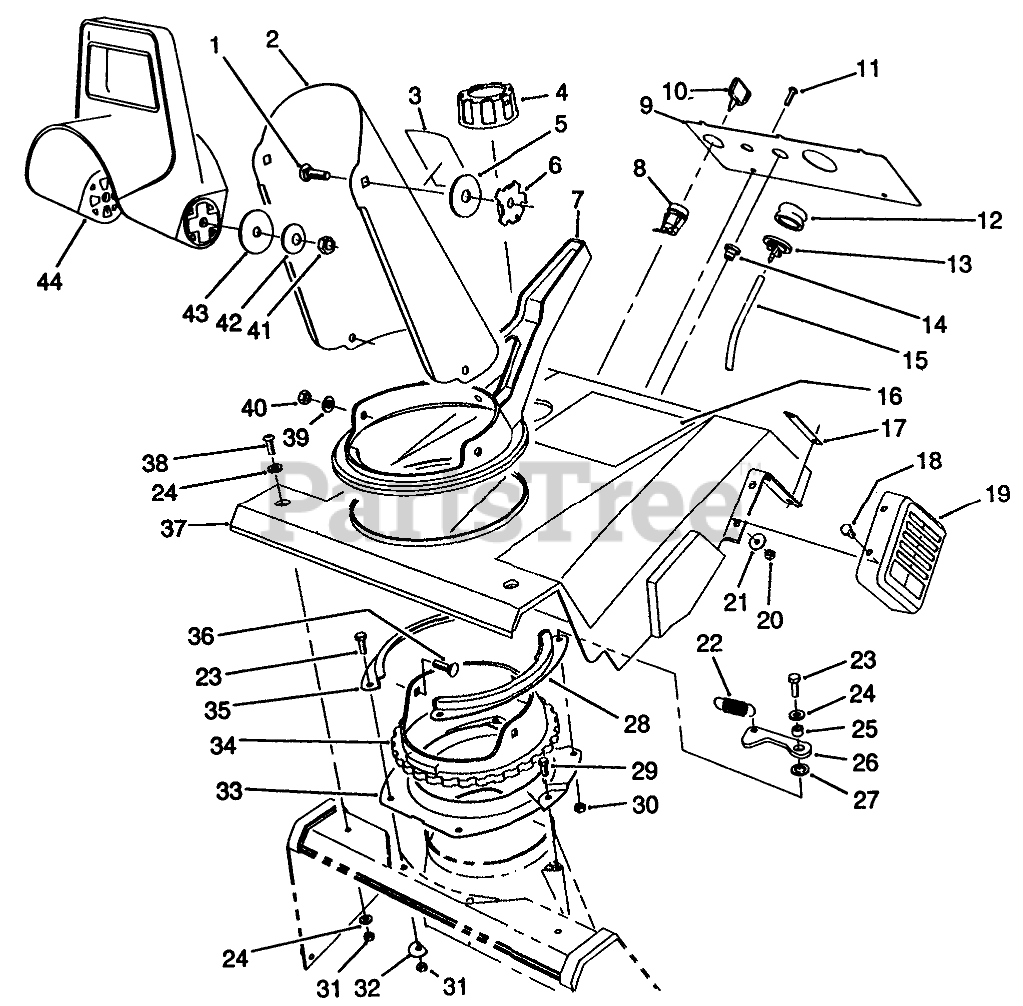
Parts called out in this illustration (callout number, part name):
1	SCREW-CARR
2	Discharge Chute Assembly (Incl. Ref. #3)
3	Decal-Danger
4	GAS CAP ASSEMBLY
5	WASHER-RUBBER
6	PLATE-FRICTION
7	CHUTE - HANDLE
8	SWITCH
9	CNTRL PANEL/SILK SCREEN
10	KEY-IGNITION
11	SCREW-SHWH, THREAD FORMING
12	BULB-PRIMER
13	BODY-PRIMER
14	GUIDE-ROPE, STARTER
15	HOSE-PRIMER
16	DECAL - CCR1000
17	MUFFLER SHIELD SPACER
18	SCREW-HWH
19	Guard-Muffler
20	NUT-LOCK, NI
21	WASHER-FLAT
22	OBS DETENT SPRING
23	SCREW-HH
24	WASHER-FLAT
25	SPACER-BLADE, ROTOR
26	DETENT
27	Washer-Special
28	Retainer-Chute Ring
29	SCREW-PLASTITE
30	NUT-LOCK, NI
31	NUT-LOCK, NI
32	Washer
33	Ring-Chute Support
34	GEAR RING, CHUTE
35	Retainer-Chute Ring
36	SCREW-CARR
37	Shroud-Upper
38	SCREW-PPH
39	WASHER-FLAT
40	NUT-KEPS
41	NUT-LOCK, NI
42	WASHER-BELLEVILLE
43	WASHER-FLAT
44	CHUTE-DEFLECTOR
